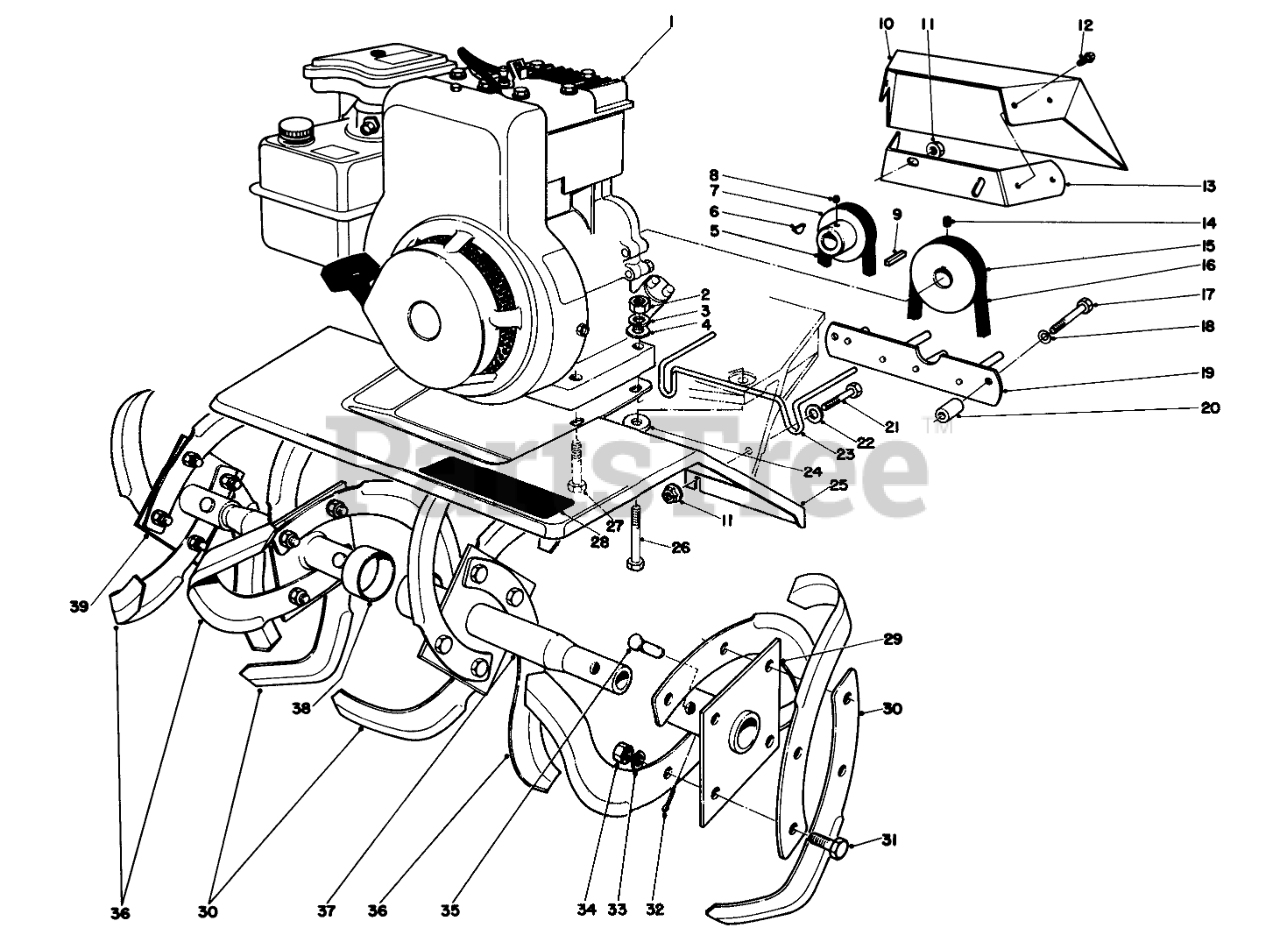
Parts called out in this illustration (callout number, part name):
1	Engine
2	NUT-HEX
3	Lockwasher
4	WASHER-PLAIN
5	V-BELT
6	HI PRO KEY
7	Pulley-Engine Rev.
8	SCREW-HSH
9	KEY-SQUARE
10	PULLEY GUARD
11	NUT-LOCK, HHF
12	SCREW-HWHTF
13	Strap-Belt Shield
14	Set Screw
15	ENGINE PULLEY
16	8070 Lanyard
17	SCREW-HH
18	WASHER-LOCK
19	Belt Guide
20	Spacer
21	SCREW-HH
22	WASHER-FLAT
23	BELT GUIDE
24	WASHER-FLAT
25	TINE SHROUD
26	SCREW-HH
27	SCREW-HH
28	Decal "Gear Drive"
29	Axle L.H.Outer
30	RH TINE
31	SCREW-HH
32	PIN-COTTER
33	WASHER-LOCK
34	NUT-HEX
35	TINE PIN
36	LH TINE
37	Axle L.H. Inner
38	Axle R.H. Inner
39	Axle R.H. Outer
